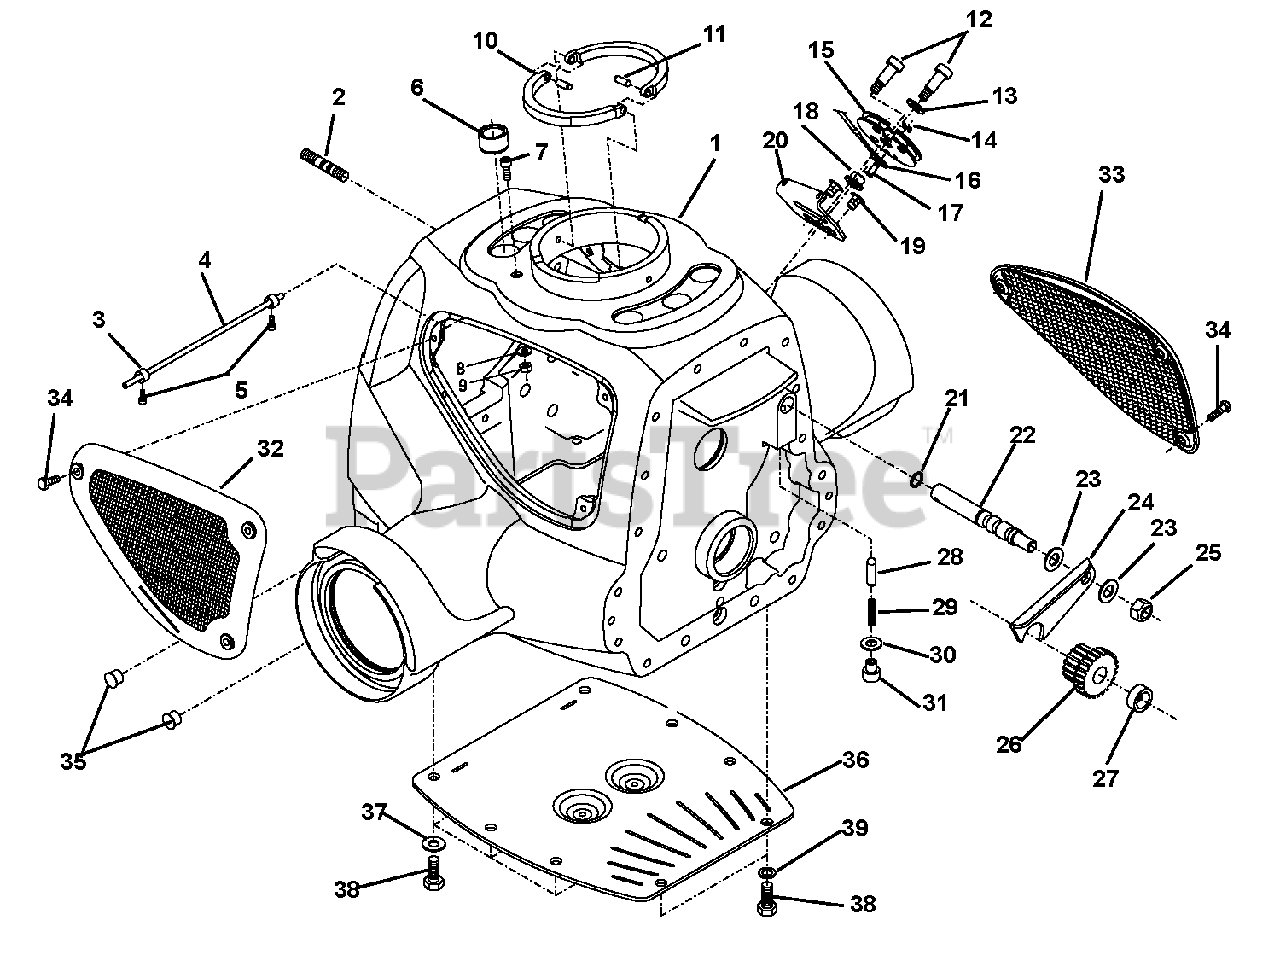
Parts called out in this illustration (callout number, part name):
2	Bolt, Stud
3	Bolt, Hex D931 M8 x 70
4	Safety, Rod
5	Screw, D912 M4 x 8
7	Screw, D912 M6 x 15
8	Washer, Form M6.1/14.2 x 1.4
9	Nut, Hex D934 M6
10	Ring, Pressure
11	Pin, Straight D6325 M6 x 18
12	Bolt, Hex M8
13	Washer, D125 10.5 x 21 x 2/3
15	Gear, Clutch
16	Cable, Shift
17	Washer, D9021 10,5 x 30 x 2,5
19	Bolt, D7991 M8 x 16
20	Guide, Cable
22	Rod, Control
23	Screw, Truss Head D603 M8 x 20
24	Fork, Shift
25	Nut, Lock D980V M12
26	Gear, Clutch
27	Ring, Distance
28	Pin, Lock
29	Spring, Pressure
30	Washer, Form Steel 10.2/20.25 x 1.6
32	CPL, Lever Positive 20-29
34	Bolt, Hex D933 M6 x 20
36	Assembly, Base
37	Washer, M10
38	Bolt, Hex D933 M10 x 25
39	Washer, Form Z 10.2/16.1 x 1.6
